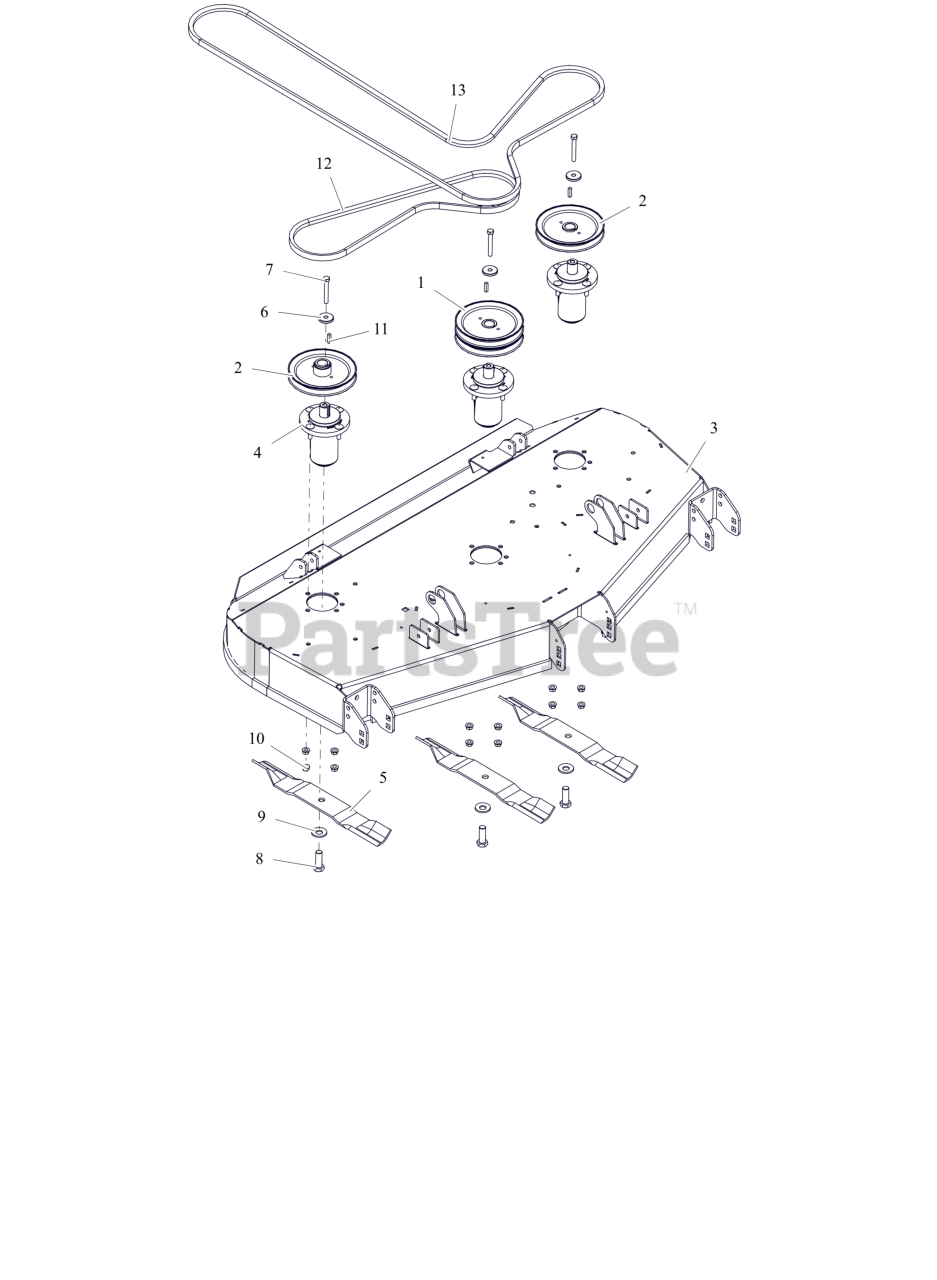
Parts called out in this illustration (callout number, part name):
1	PULLEY, DOUBLE-1"ID X 6.75"OD
2	PULLEY, V-1" ID X 6.75" OD
3	WLDMT, 52 REAR DISCH DECK CE (ORANGE)
4	ASM, MAINT FREE ALUM SPINDLE
5	BLADE, 18"
6	RETAINER, SHEAVE
7	BLT, HEX .38-16X2.75 G8 ZCC
8	BLT, HEX .62-18X1.75 G8 ZCC
9	WSHR-BLVL .669X1.535X.138
10	NUT-LK-CTR-FLG .375-16 GF ZCC
11	KEY, SQ .25X.25X1.00 RC 40-50
12	V-BELT, B-COGGED
13	V-BELT, HB SECTION
